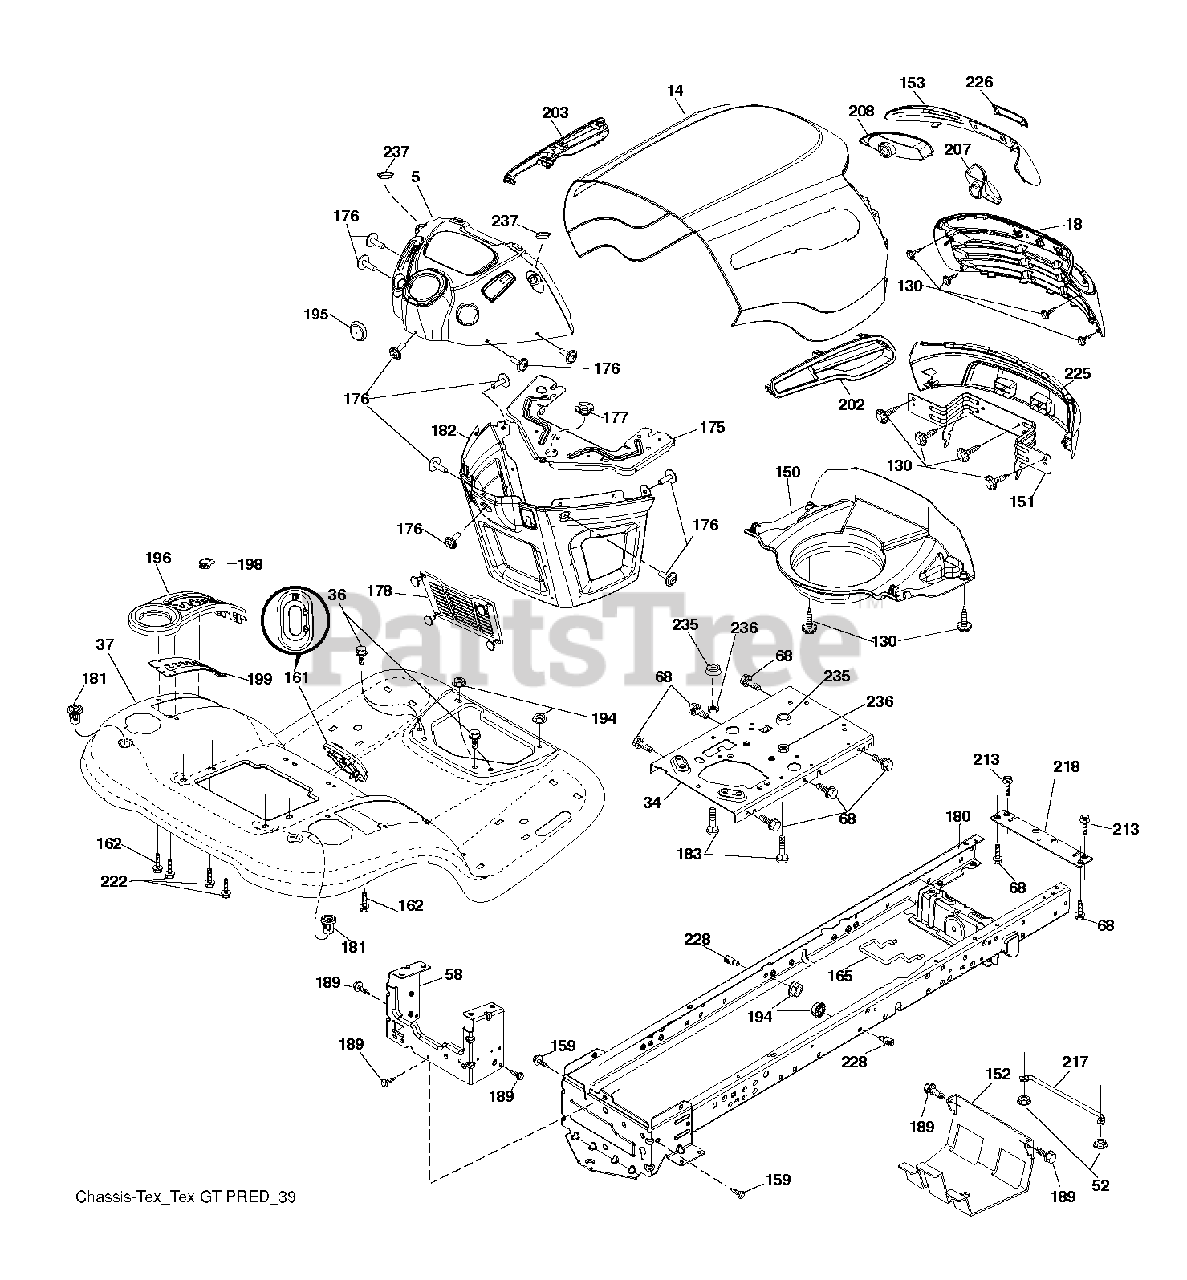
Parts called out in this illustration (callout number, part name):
34	PLATE.ENGINE.WELDED.CHASSIS
36	SCREW 5/16"
52	LOCKNUT
58	DRAWBAR.UPPER.2PC,LRG.FENDER
130	SCREW.#10 X 0.750.BOS THREAD
152	SHIELD BROWNING
159	SCREW, 3/8-16X3/4
161	CONSOLE.FUEL.WINDOW.STGT.BLACK
162	SCREW.HI-LO.CONSOLE
165	SUPPORT.TANK.REAR.W/TE
175	PLATE.CROSSMEMBER.HUSQ
176	SCREW.#10-24X5/8.RN.QU
177	BUSHING,STEERING
178	CARGO.ASM.NET.TXGT.W/C
180	CHASS.WLDMNT.TLT.12GA/2PC.20"
181	FEND/FTRST.PCH.CPH.NFW
182	DASH.LOWER.COMMON.12V.ADAPTOR
183	BOLT.5/16-18X1-1/4 FULL THD
189	SCREW
194	NUT LOCK HEX FLANGE 5/16-18
195	PLUG.HOLE.DASH.LOWER.12V.BLK
199	PLATE DECK LIFT
213	BOLT
217	ROD.PIVOT.HOOD
218	X-PIECE.HOOD.STOP.NON/
222	SCREW.1/4-20X5/8
228	STUD.FASTNER.W/ANTI-ROTATE
235	SPACER FENDER
236	NUT.CENTERLOCK.5/16-
237	PLUG.MOUNT.CARGO.BLK
